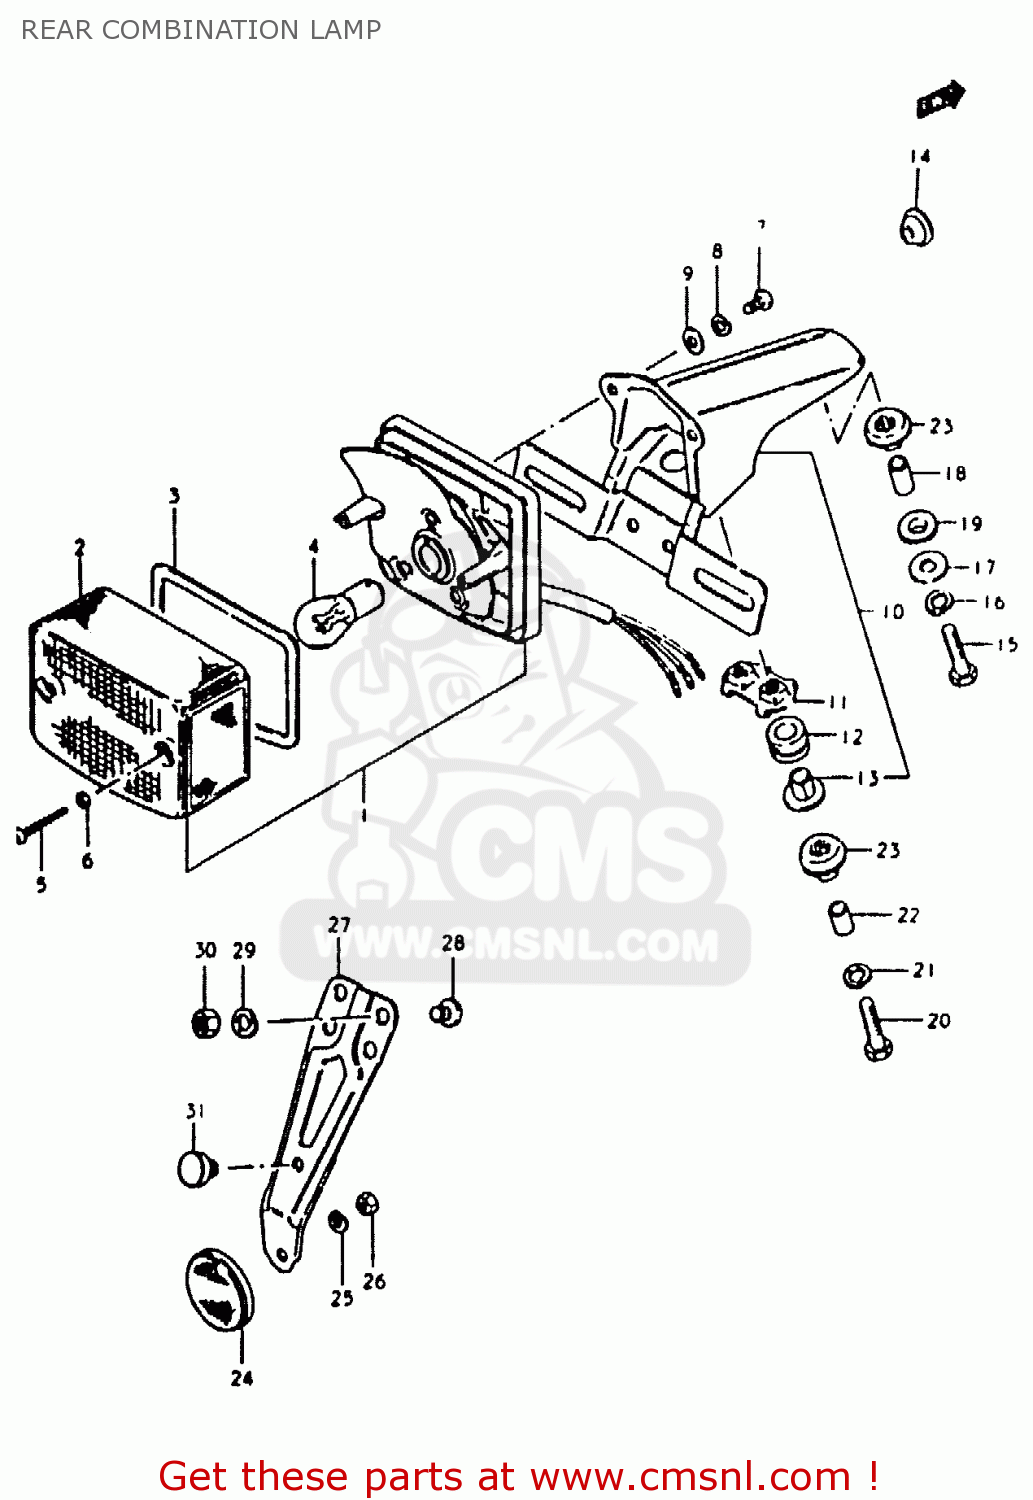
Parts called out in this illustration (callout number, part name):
1	LAMP UNIT, TAIL
2	LENS
3	GASKET (NAS)
4	BULB (6V,21/5W)
5	SCREW
6	GASKET (NAS)
7	SCREW
8	LOCK WASHER
9	WASHER
10	BRACKET ASSY
11	PLATE
12	CUSHION
13	SPACER
14	GROMMET
15	BOLT
16	LOCK WASHER
17	WASHER
18	SPACER
19	CUSHION
20	BOLT 6X40
21	LOCK WASHER
22	SPACER (6.8X10X11.5)
23	CUSHION
24	REFLEX REFLECTOR,RR
25	LOCK WASHER
26	NUT
27	BRACKET
28	SCREW
29	LOCK WASHER
30	NUT
31	CUSHION
